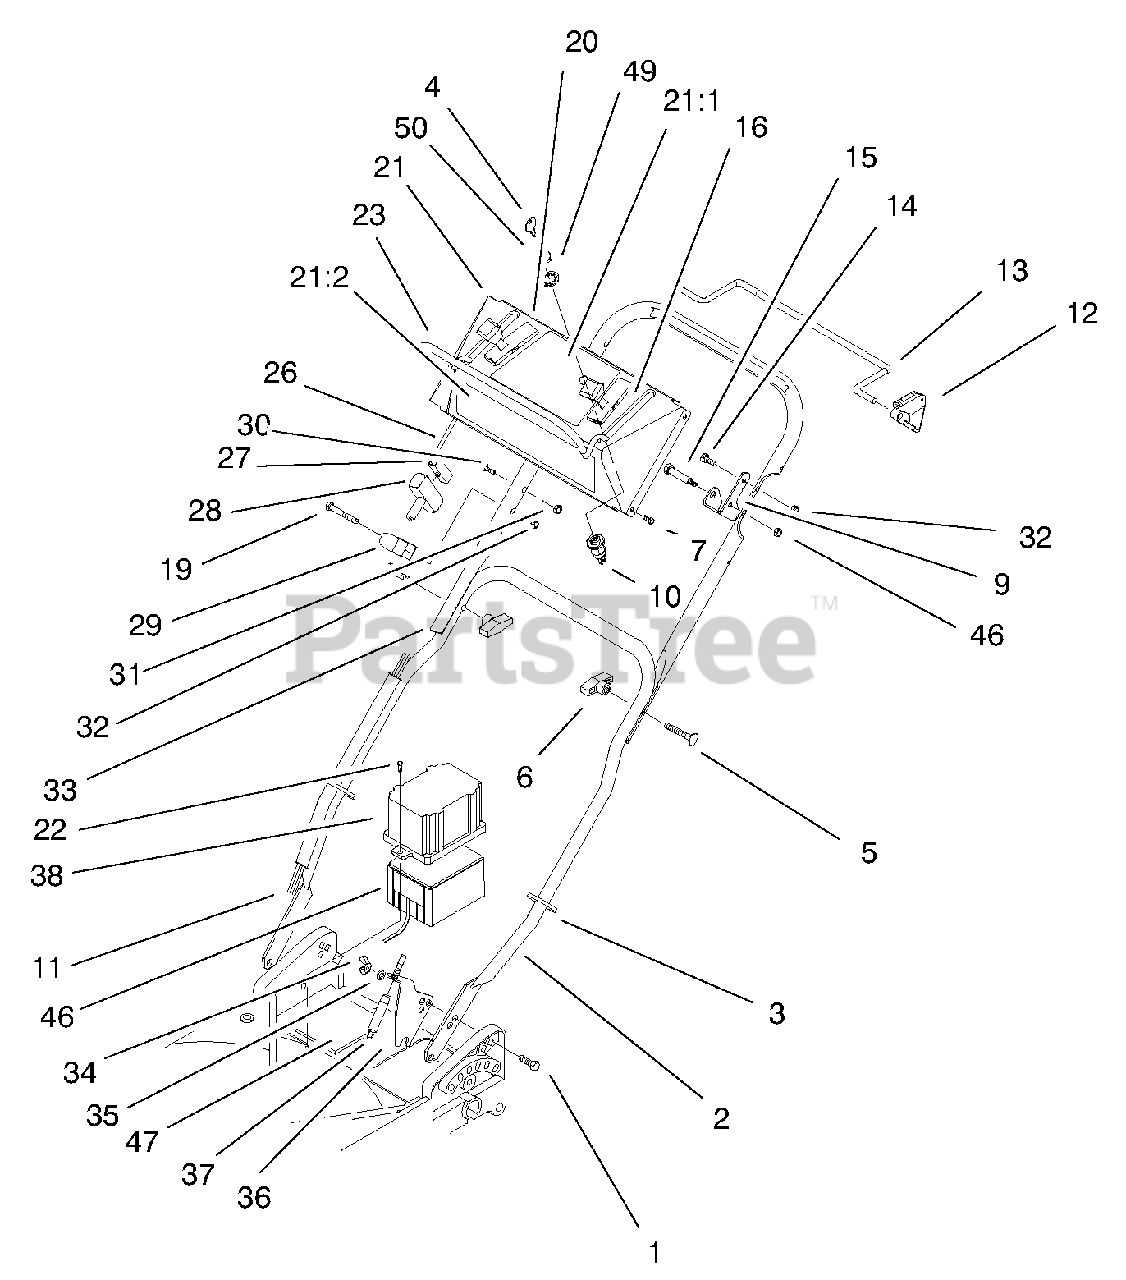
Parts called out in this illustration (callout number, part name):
1	Bolt-CARR
2	Handle Section-Lower
3	Tie Strap
4	Key-Ignition
5	Screw-Handle
7	Screw-Phil
8	Nut-Lock
9	Bail Stop Bracket
10	Switch-Starter
11	ASM-Wire
12	Stop-Pivot
13	Bail-Sp Control
14	Screw-HH
16	Throttle Cable
19	Bolt-Hex
20	Control-Speed
21	Control-Console
21:1	Decal-Control Panel
21:2	Decal-Console
22	Screw-Thread Forming
23	Engine Control Bail
26	Cable-Control
27	Clip-Rope
28	Handle-Starter
29	Guide-Rope
30	Handle Screw
31	Bracket-Cable Anchor
32	Nut-Lock
33	Handle-Upper
35	Washer-Lock
36	Bracket-Traction Cable
38	Case-Battery
46	Battery Pack
47	Pad Battery
49	Washer-Lock
50	Nut-HH (F/W Sw)
